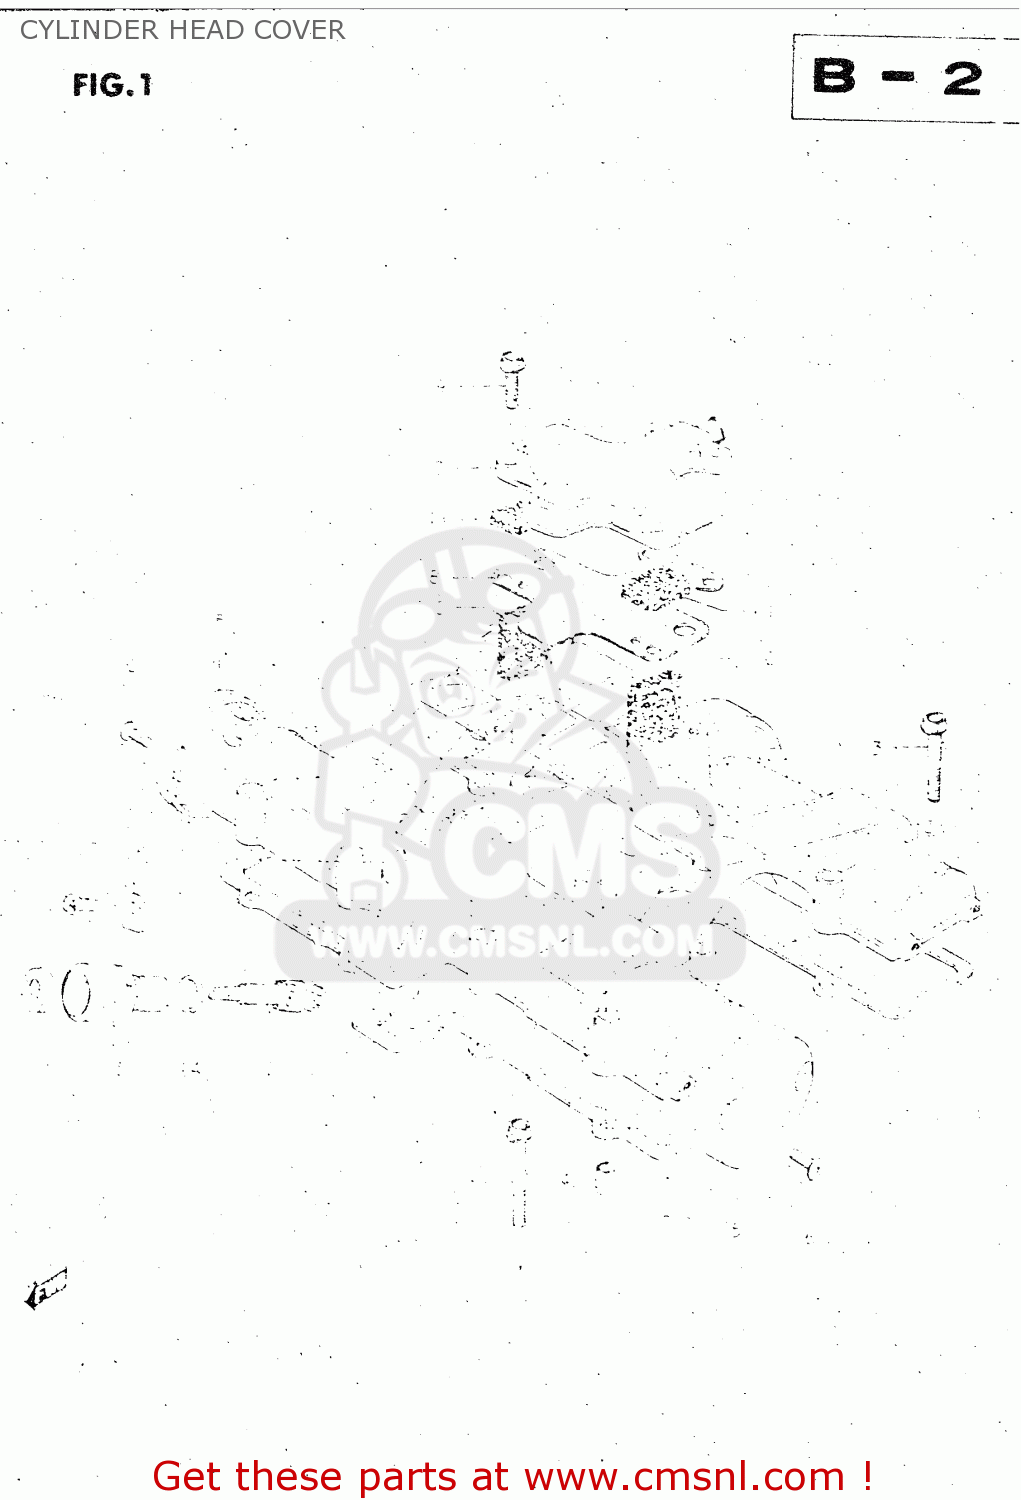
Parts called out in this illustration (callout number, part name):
1	COVER,CYLINDER HEAD
2	GASKET,CYLINDER HEAD COVER (MCA)
3	BOLT
4	PIN(6.2X8X11)
5	CAP,CYLINDER HEAD COVER
6	SCREW 5X12
7	COVER,BREATHER
8	GASKET (MCA)
9	BOLT,REAR
10	COVER,BREATHER
11	SEPARATOR,OIL BREATHER
12	GEAR,TACHOMETER DRIVEN
13	SLEEVE,TACHOMETER DRIVE
14	SEAL,TACHOMETER DRIVEN
15	SEAL,OIL(5X12X8)
16	PLATE,TACH DRIVE GEAR SLEEVE
17	SCREW(5X12)
